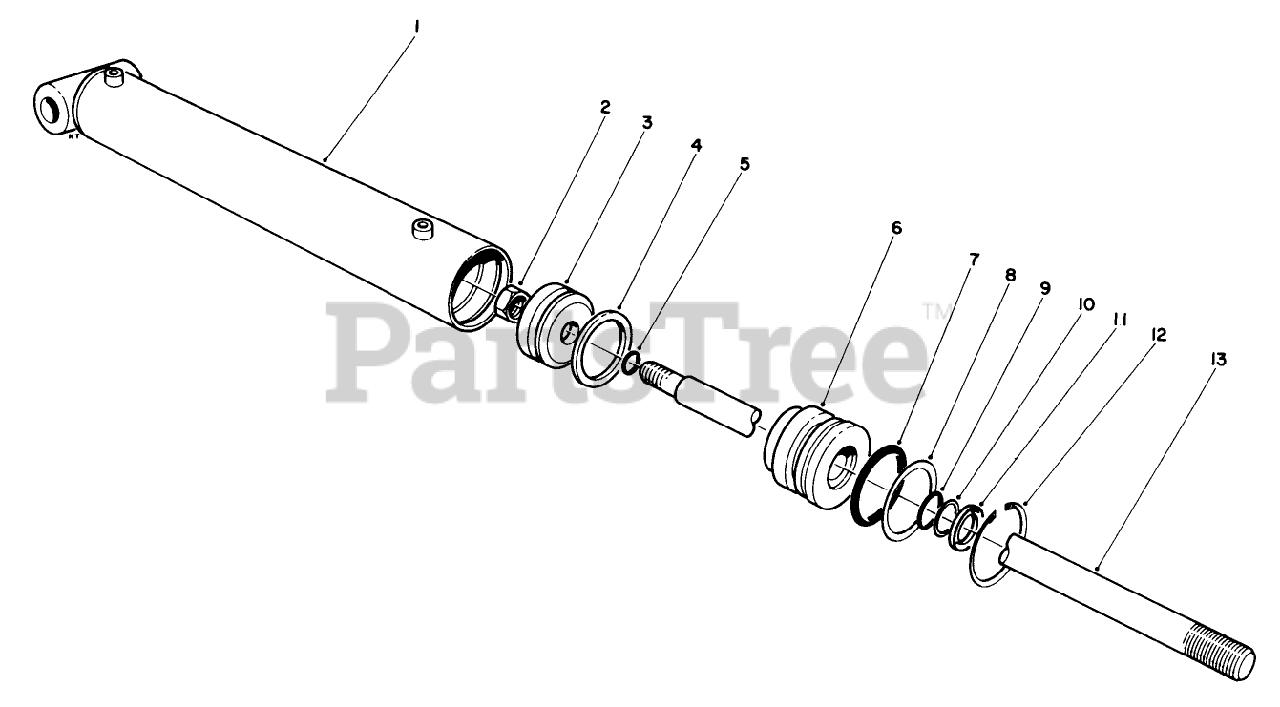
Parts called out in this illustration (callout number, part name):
1	Barrel
2	LOCKNUT
3	PISTON
5	"O"Ring
7	"O"Ring
9	"O"Ring
12	RING-RETAINING
13	SHAFT
